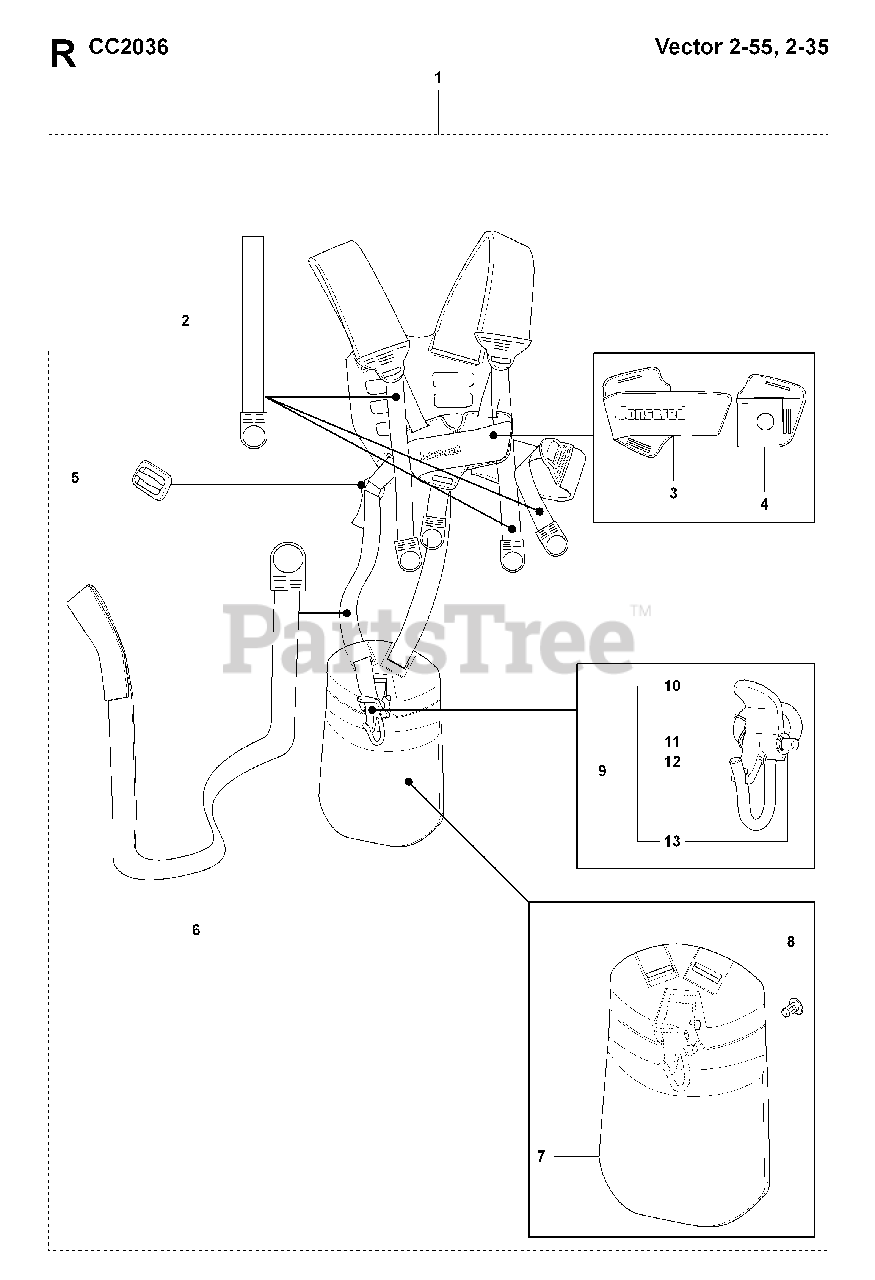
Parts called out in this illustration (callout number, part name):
1	HARNESS "VECTOR" 2-55
1	HARNESS COMPLETE
3	FRONT PIECE
4	FRONT PIECE
5	CLIP
7	PROTECTOR
9	HARNESS HOOK, COMPLETE
